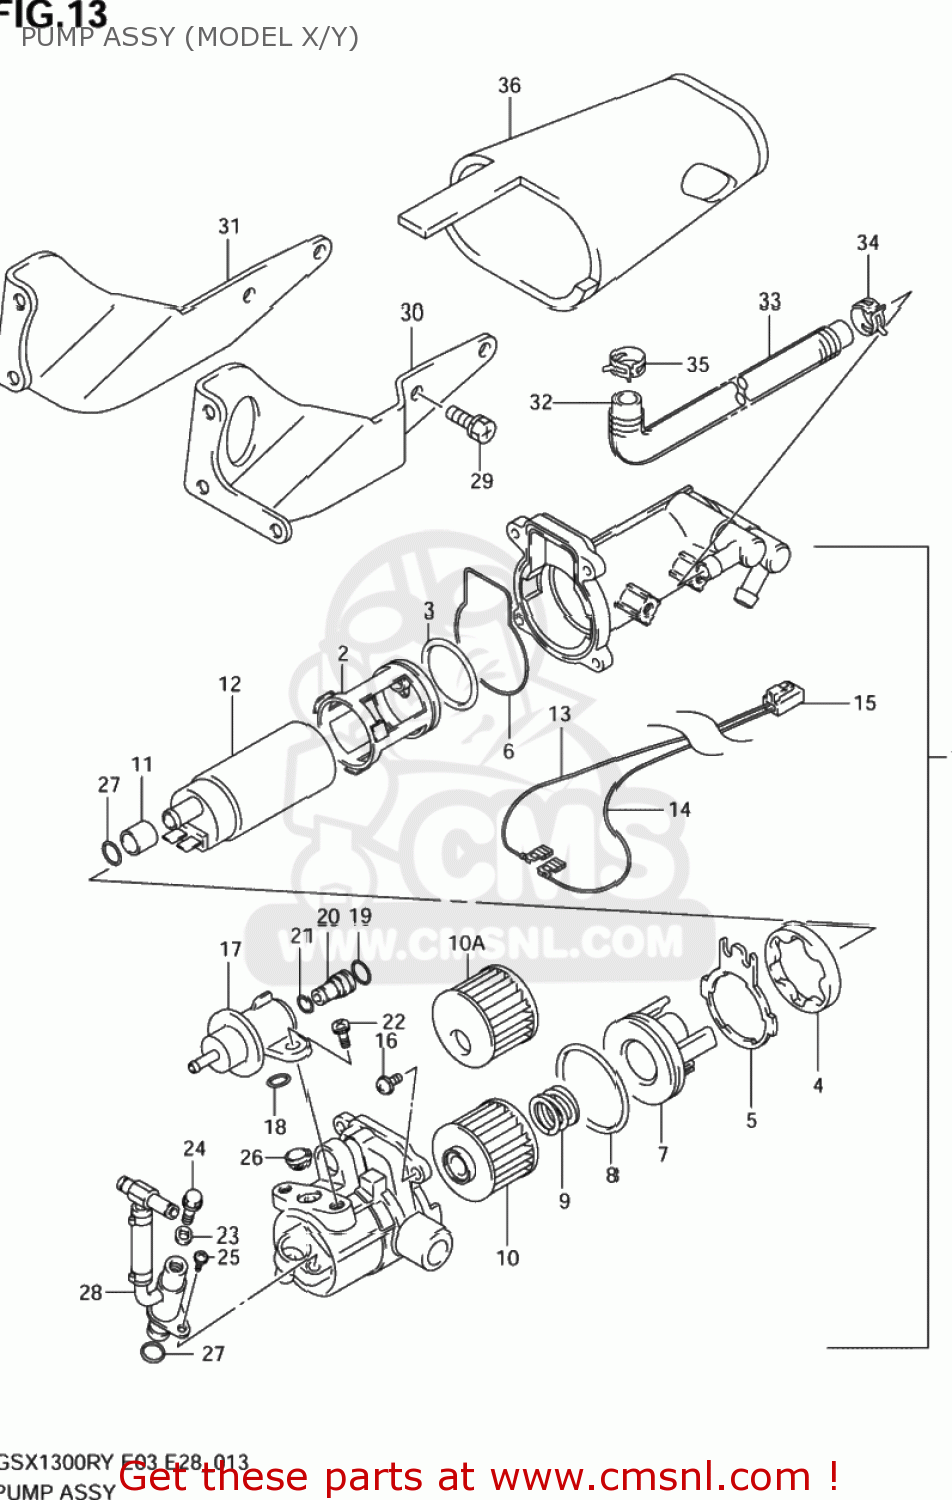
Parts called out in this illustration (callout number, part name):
1	PUMP ASSY,FUEL
2	INSULATOR
3	O RING
4	INSULATOR
5	PLATE,STAY
6	PACKING (NAS)
7	COLLAR
8	O RING
9	SPRING
10	STRAINER,FUEL
10A	STRAINER,FUEL
11	COLLAR
12	PUMP ASSY,FUEL
13	HARNESS(+)
14	HARNESS(-)
15	HOUSING,CONNECTOR
16	SCREW
17	REGULATOR ASSY,PRESSURE
18	O RING
19	O RING
20	JOINT
21	O RING
22	SCREW
23	PACKING (NAS)
24	BOLT
25	SCREW
26	SCREEN,FUEL STRAINER
27	O RING
28	PIPE SET
29	BOLT
30	PLATE,FUEL PUMP STAY,L
31	PLATE,FUEL PUMP STAY,RIGHT
32	HOSE,FUEL RETURN
33	SPRING,FUEL RETURN HOSE
34	CLIP
35	CLIP
36	COVER,FUEL PUMP
